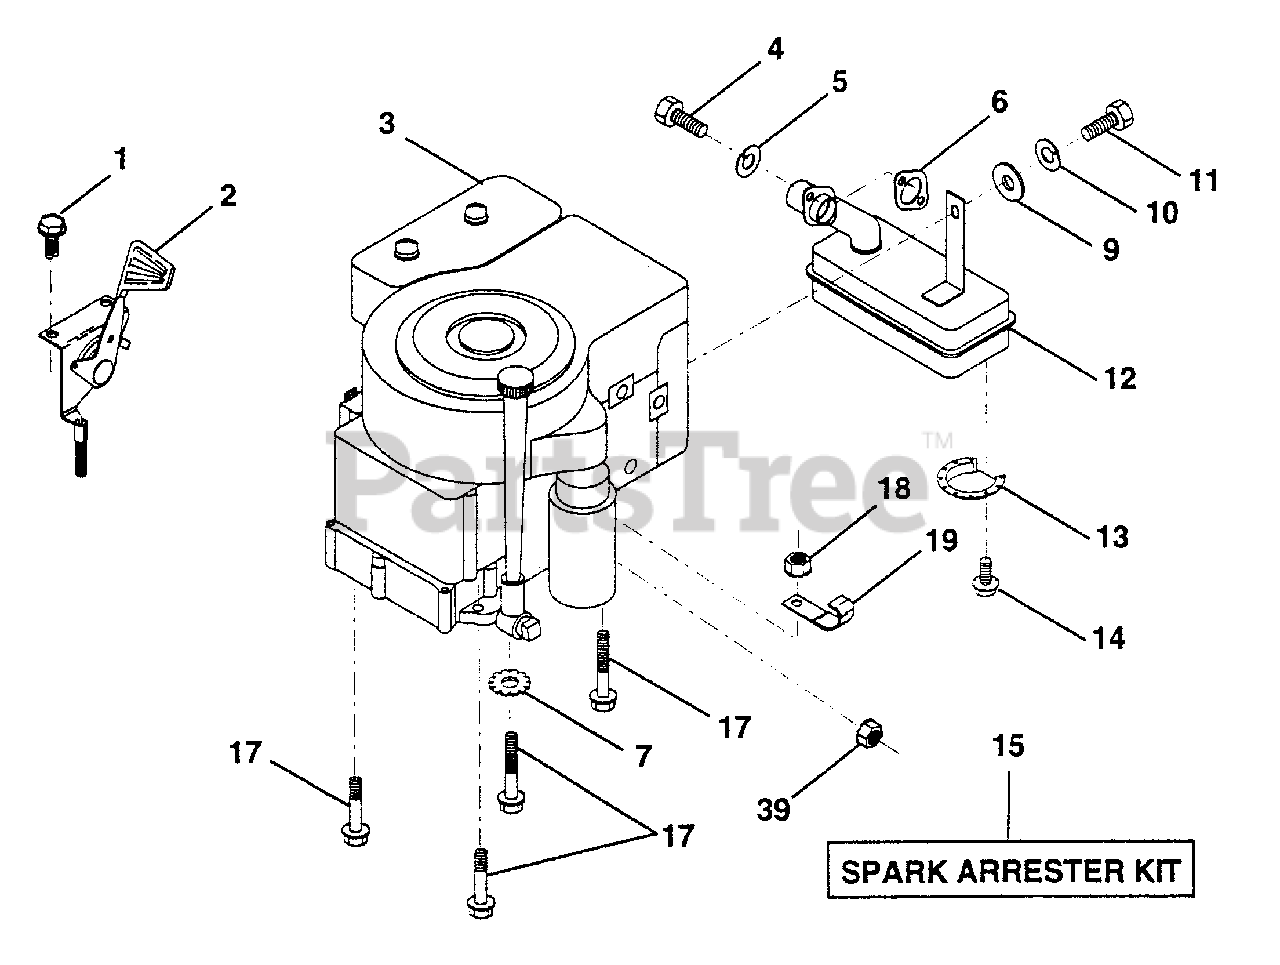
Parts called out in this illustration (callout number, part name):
1	Screw, Hex Head, Thread Cutting 1/4-20 x 1 /2
2	Control, Throttle
3	Engine, B&S, 13 HP, Vanguard Dual Model Number 28P777
5	Washer, Lock, Hvy Hlcl Spring 5/16
6	Gasket Eng.
7	Washer Lock Ext. Tooth 3/8
10	Washer, Lock Hvy Helical 1/4
11	Screw 1 /4-20 x 1.00 77
13	Deflector Muffler
14	Screw
15	Arrester, Spark
16	Stop Throttle 3000 RPM
17	Screw Thdrol 3/8-16 x 1-1/2
18	Nut, Lock Hex W/Ins. 3/8-16
19	Clip, Fuel Line
24	Screw Thdrol 3/8-16 x 1-1/4
25	Screw Hex SKT 5/16 UNC x 3/4
26	Washer 9/32 x 3/4 x 10 Ga.
39	Nut, Keps, Hex Hd. 1/4-20
